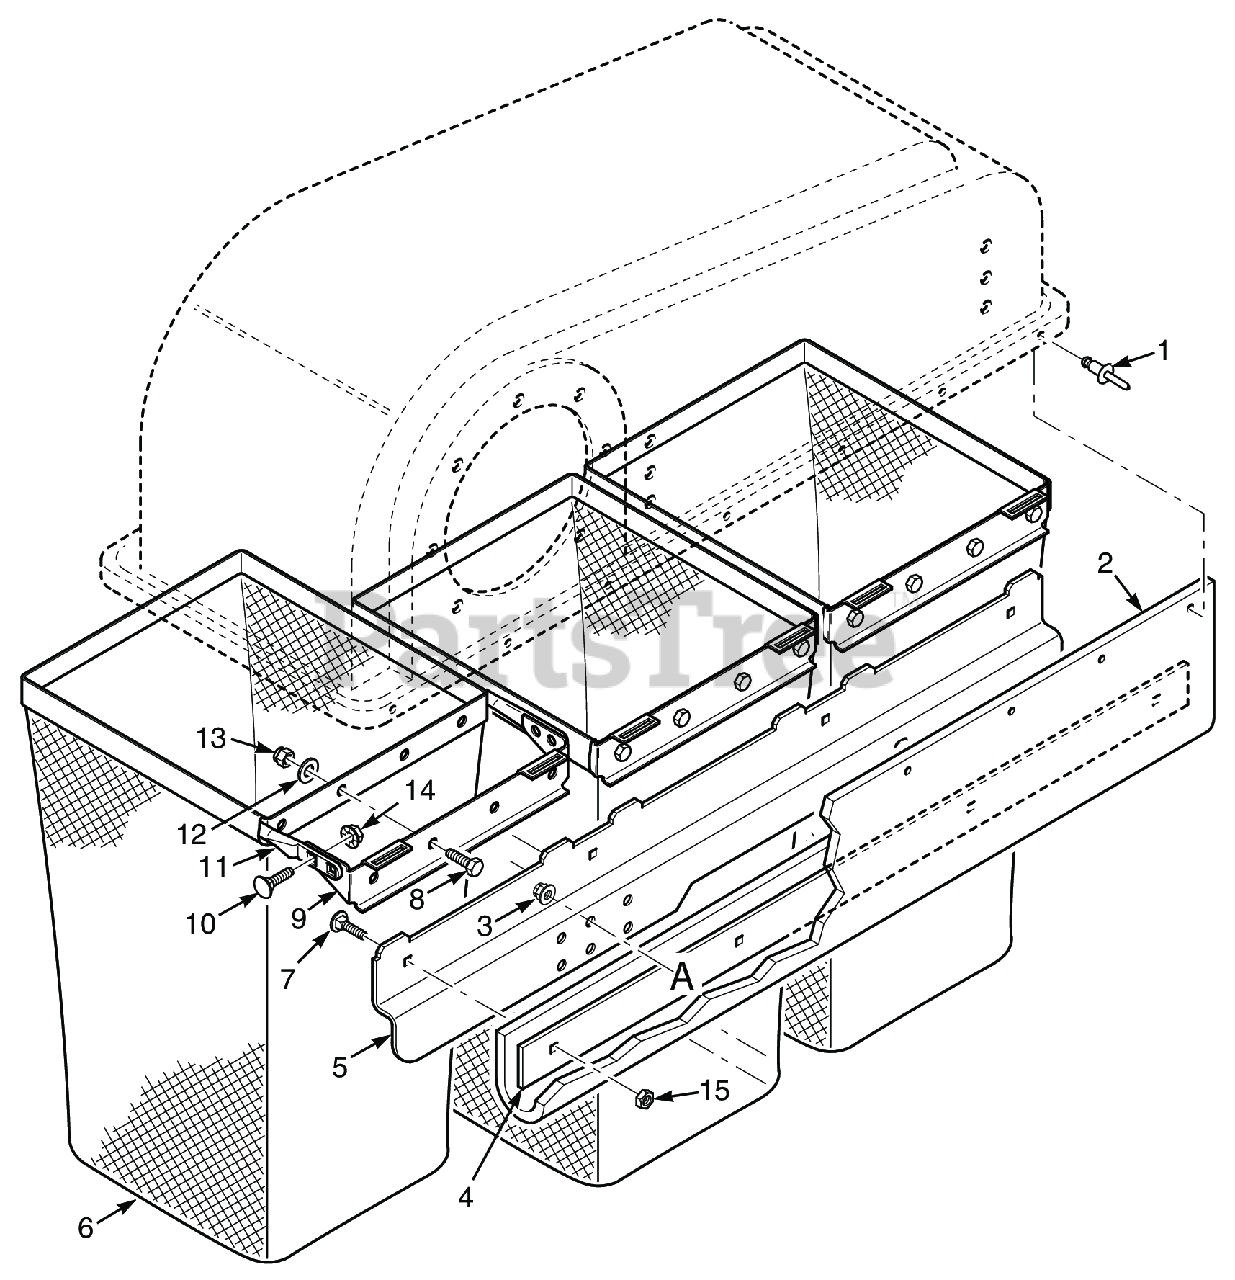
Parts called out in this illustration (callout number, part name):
1	Pop Rivet, 3/16 x .652"
2	Seal, Hood
3	Nut, Flange Elastic Stop Nut, 3/8-16
4	Retainer, Seal
5	Support Weldment, Bag Frame
6	BAG ASSY, GC
7	Serr. Fl. Hex Head CPSCR, 1/4-20 x 3/4"
8	BOLT, SERRATED FLANGE HEX HEAD 5/16-18 X 3/4"
9	Mount, Bag Frame Tube
10	Bolt, 5/16-18 x .75 RHSN Carriage
11	Tube, Bag Support
12	Flatwasher, 5/16-.375 x .875 x .083 (35BV & 37BV-EFI)
13	HEX NUT, ELASTIC STOP LOCK, 5/16-18
14	Nut, Serrated Flange 5/16-18 (Right Front Engine Mounting, Briggs and Kohler Only)
